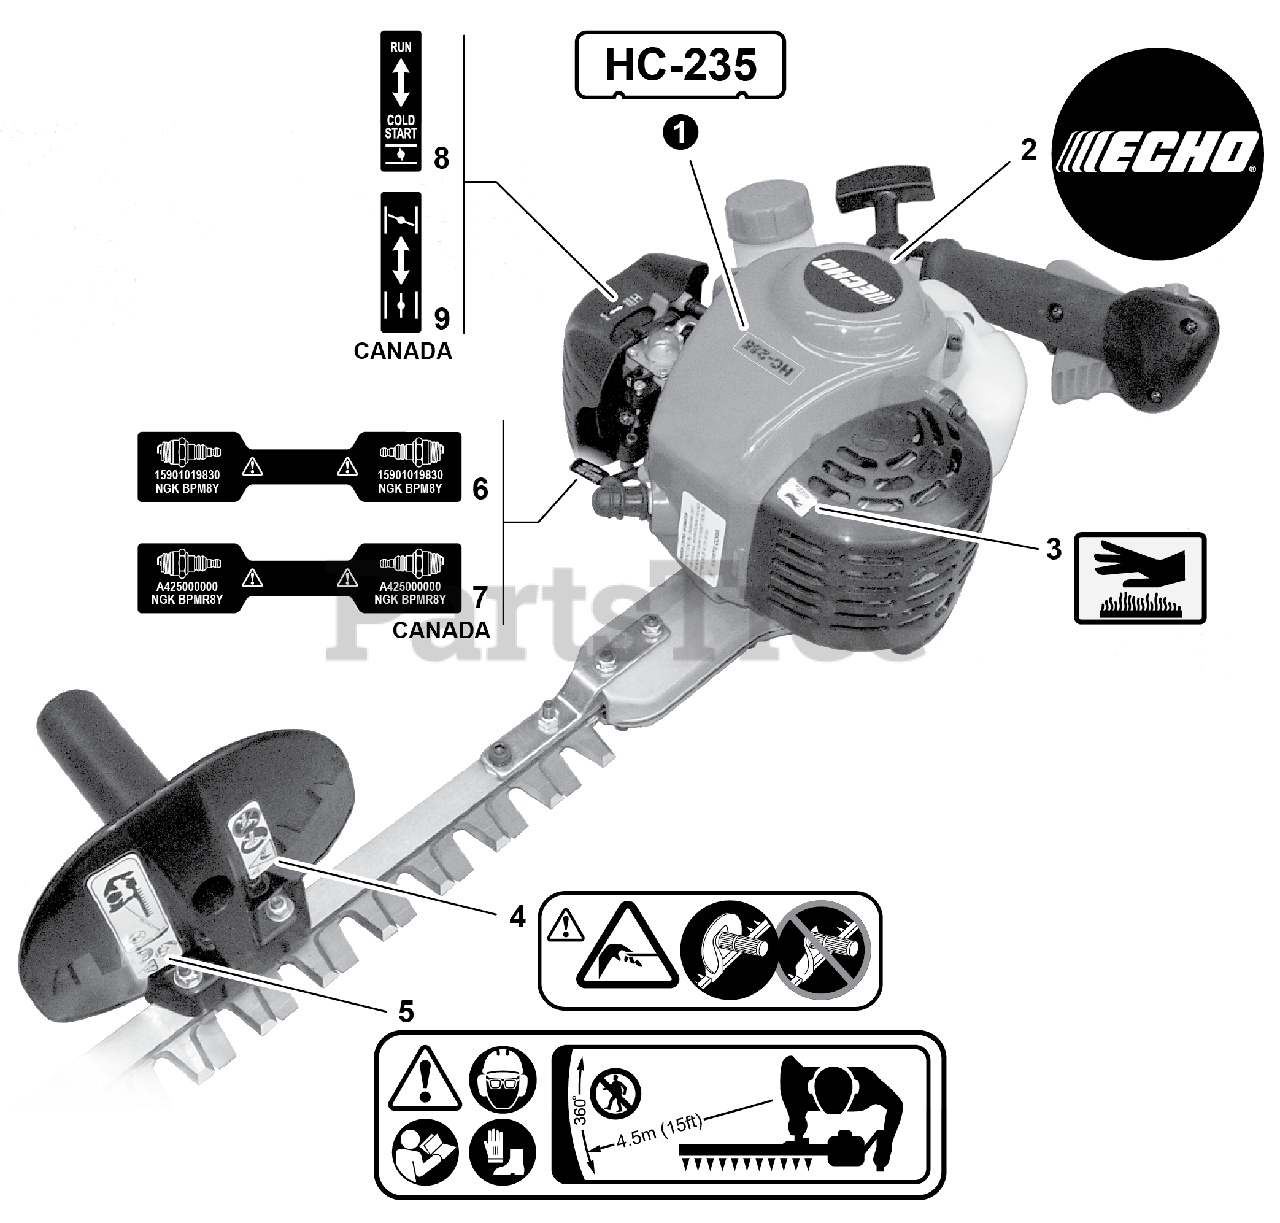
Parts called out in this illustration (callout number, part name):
1	LABEL, MODEL - HC-235
2	LABEL, RECOIL STARTER
3	LABEL, CAUTION - HOT
4	LABEL, CAUTION - ISO
5	LABEL, CAUTION
6	LABEL, SPARK PLUG - BPM8Y
7	LABEL, SPARK PLUG - BPMR8Y
8	LABEL, CHOKE
9	LABEL, CHOKE
